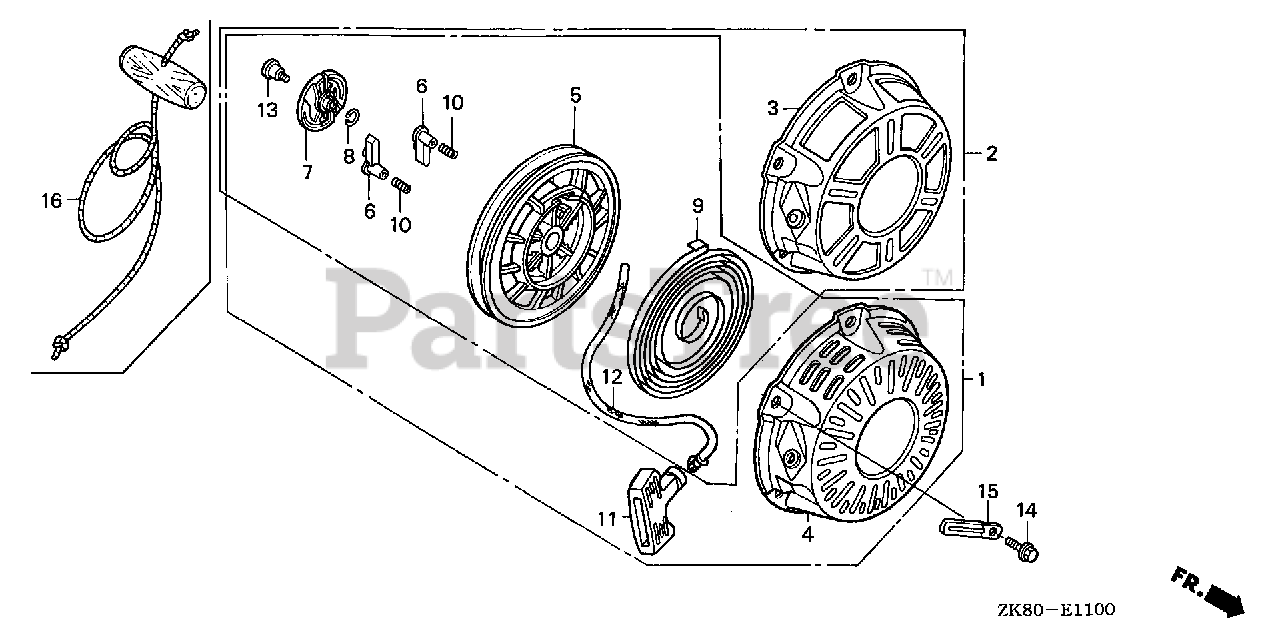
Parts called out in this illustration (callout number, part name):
1	STARTER ASSY., RECOIL *R280* (POWER RED)
1	STARTER ASSY., RECOIL *NH1* (BLACK)
4	CASE, RECOIL STARTER *R280* (POWER RED)
4	CASE, RECOIL STARTER *NH1* (BLACK)
5	REEL, RECOIL STARTER (NATURAL)
6	RATCHET, STARTER
7	GUIDE, RATCHET
8	SPRING, FRICTION
9	SPRING, RECOIL STARTER
10	SPRING, RETURN
11	GRIP, STARTER
11	KNOB, RECOIL STARTER
12	ROPE, RECOIL STARTER
13	SCREW, SETTING
14	BOLT, FLANGE (6X10)
